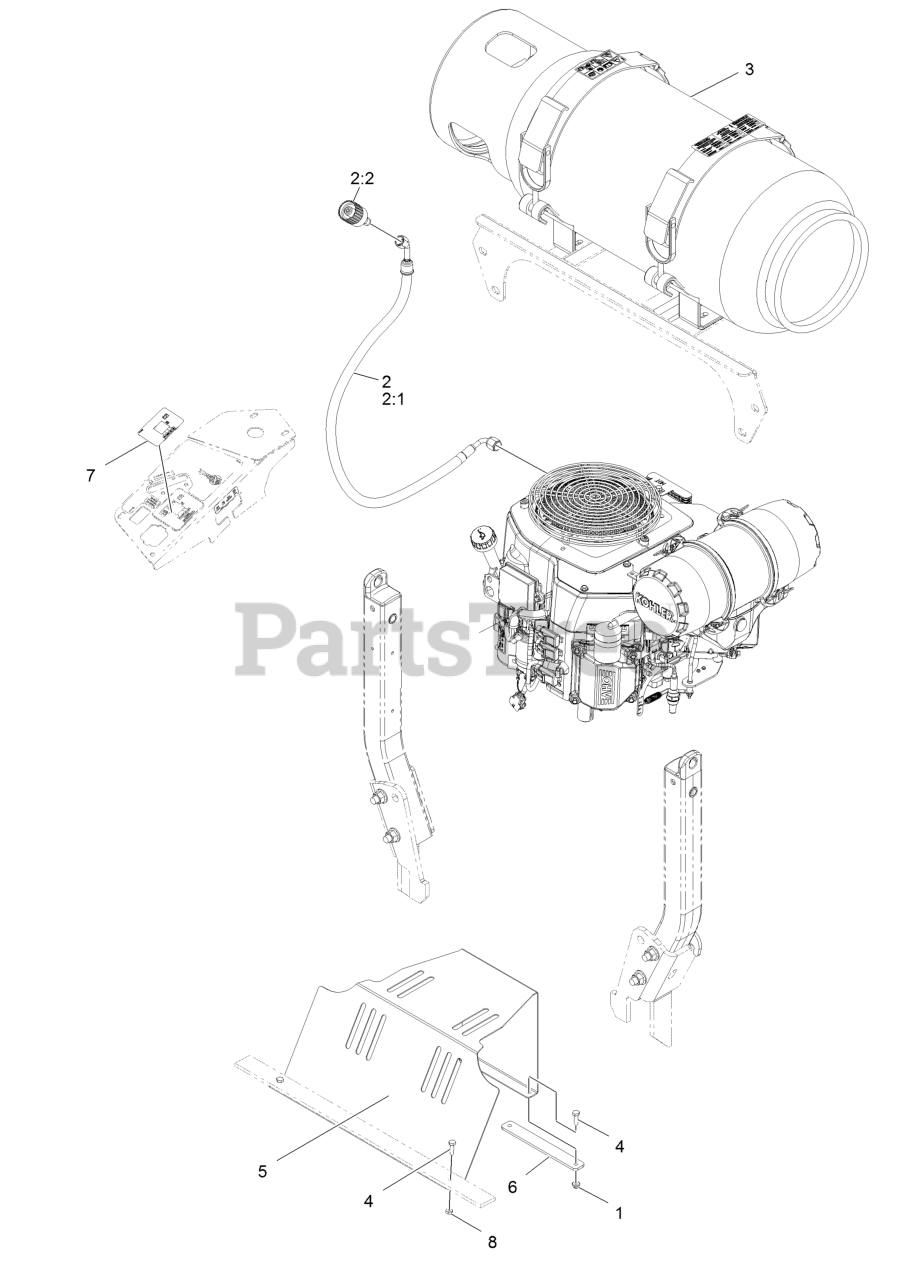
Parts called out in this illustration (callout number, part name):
2	LPG HOSE ASM
2:1	HOSE ASM, LPG
2:2	CONNECTOR-LP, STRAIGHT
3	TANK-LPG
4	SCREW-HH
5	SHEILD-FAN
7	DECAL-METER, HOUR
8	NUT-JAM
